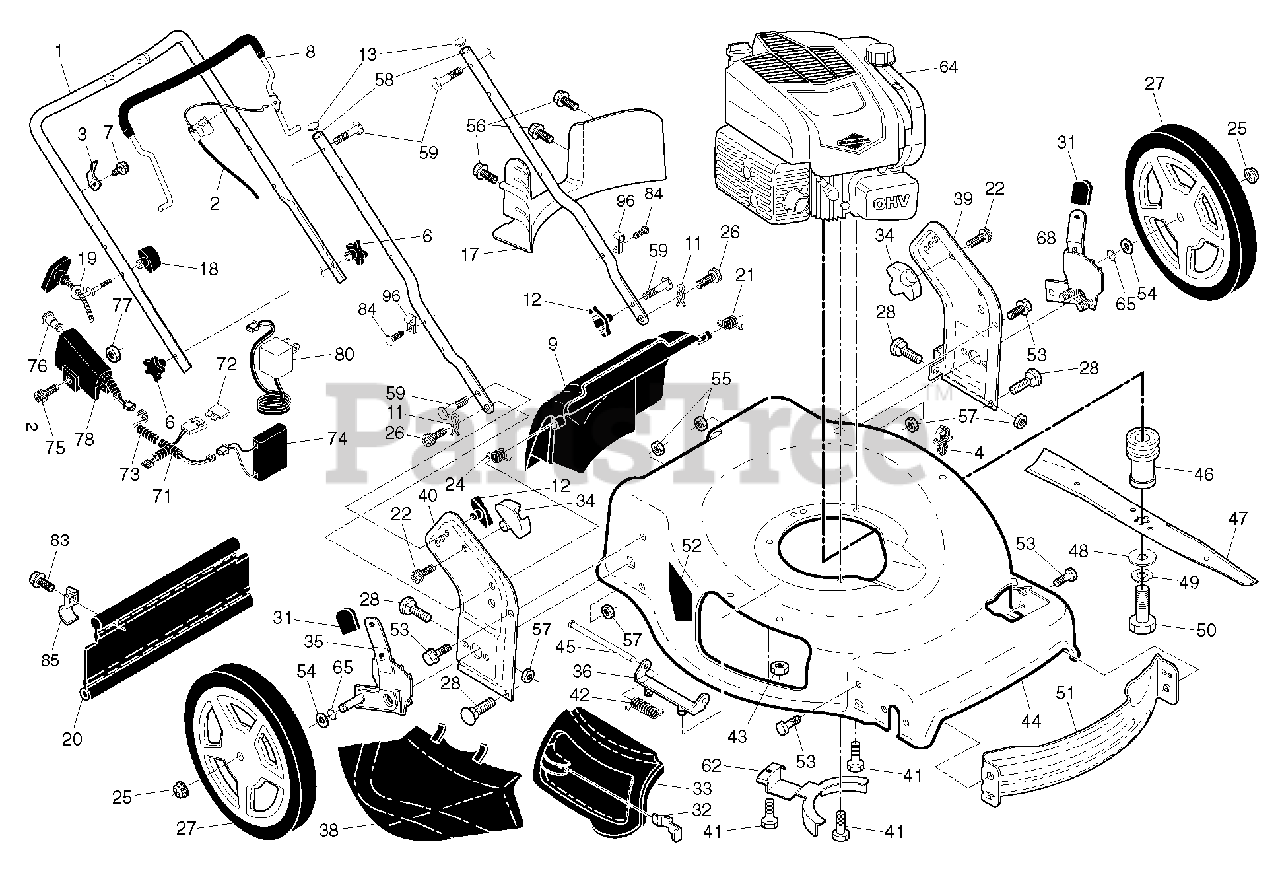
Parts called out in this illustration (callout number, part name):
1	HANDLE.UP.DST.SS/VS.FG/RG.NHB
2	CABLE.MZR.FGD.PLUS
3	BRACKET.UPSTOP.RT
4	PUSH CLIP
6	KNOB.HANDLE.PLASTIC.STAR.BLACK
8	Bail, Om Strt Mzr Marig 421
9	DOOR.REAR.22PLUS.MB.FGD.SAFETY
11	COTTER.HAIRPIN.DOOR/HANDLE.PIV
13	PLUG.PLASTIC.7/8".14-20.GAUGE
17	BAFFLE.22PLUS.FGD.REAR.
18	T-KNOB.NEW ROPE GUIDE
19	Rope Guide, Blk Zinc Chrom
20	SKIRT.REAR.22PLUS.RGD/FGD.NEW
21	SPRING.LH.GRAY
22	SCREW.PAN.HEAD.#10
24	SPRING.RH.GRAY
25	NUT.HEX.FLANGE.3/8-16.LOCKNUT
26	SCREW,DOOR/HANDLE.PIVOT
27	WHEEL.12X1.75.5SP.RAD3.MARIGOL
28	Carriage Bolt, 5/16-18 X 5/8
31	SELECTOR KNOB
32	LATCH.DOOR.ZINC
33	DOOR.MULCH.22.BLACK.MULTI-BRAN
34	BRACKET.GRASSBAG.ATTACHING.BLK
35	ADJUSTER.ASM.9POS.HW.R/R
36	BRACKET.ASM.HINGE.21.FWGD.
38	DEFLECTOR.CLIPPING.22.BLACK
39	Handle Bracket Assembly, LH 22+ Black
40	Handle Bracket Assembly, RH 22+ Black
41	BOLT 3/8-16X1-1/8
42	SPRING.TORSION
43	NUT.HEX.FLANGE.1/4
44	HOUSING.22.FWD.MC.WO.NB.BLACK
45	ROD.HINGE.21
46	ADAPTOR BLADE 25MM STAR
47	BLADE.22PLUS
48	WASHER,HARDEN
50	SCREW, HEX HD 3/8-24 X 1-3/8
51	BAFFLE.FRONT.22.PLUS
52	No Step Decal
53	BOLT.5/16HEX.WHS.HD
54	WASHER PM
55	NUT.HEX.FLANGE.1/4
56	SCREW.HX.13X.750
57	NUT.FLANGE.5/16
58	HANDLE.LOWER.22+.BT.2PC.BLK
59	BOLT, HANDLE 5/16-18X1.75
62	BRACKET.ENG/BELTKEEPER
65	O-RING..070X.487.NEOPRENE
68	ADJUSTER.ASM.9POS.HW.R/L
71	HARNESS.WB.BATTERY.FGD.22+
72	FUSE, 40A
73	HARNESS.WIRE.ES.FGD.B
74	BATTERY.12VOLT.22+.FGD.W/FOAM
75	BOLT.M6-1X40.T30
76	BUTTON.KEY CYLINDER.MARIG
77	NUT.M6-1 NYLOC
78	STARTER.ASM.PUSH.BUTTON
80	Battery Charger, 12V
83	TAPPING SCREW
84	FASTENER.PUSH.O.250X0.783
85	BRACKET.SKIRT.22+.BZP
96	CLIP.CABLE.BLK
